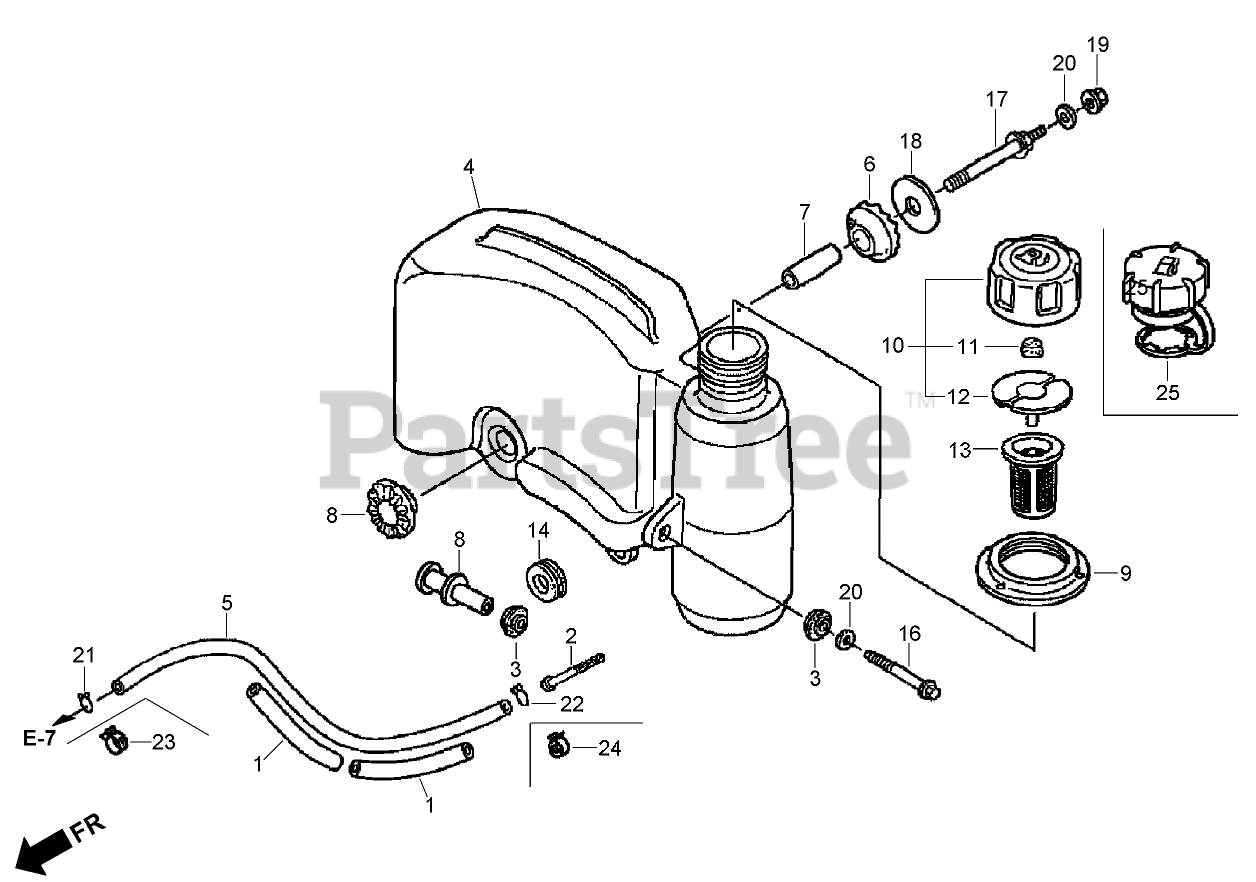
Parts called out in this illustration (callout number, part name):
1	SUPPORTER-RUBBER (107 mm)
2	FILTER-FUEL
3	RUBBER-SETTING, TANK
4	TANK-FUEL (Engine Serial No. Up To 1036455)
4	TANK-FUEL (Engine Serial No. From 1036456)
5	TUBE-FUEL (Engine Serial No. Up To 1011283)
5	TUBE-FUEL (FKM) (Engine Serial No. From 1011284)
6	RUBBER B-MOUNTING, TANK
7	COLLAR-SET, TANK
8	COLLAR-TANK
9	RUBBER-MOUNTING, TANK (Engine Serial No. Up To 1036455)
10	FUEL TANK CAP ASM (Engine Serial No. Up To 1036455)
11	SPONGE-BREATHER, FUEL CAP (Engine Serial No. Up To 1036455)
12	GASKET-CAP, FUEL (Engine Serial No. Up To 1036455)
13	GAUGE-LEVEL, FUEL
14	CUSHION-FENDER, R R
16	BOLT-FLANGE (6X47) (C T200)
17	BOLT-STAY, TANK
18	WASHER-MOUNTING, TANK
19	NUT-FLANGE (6 mm)
20	WASHER-PLAIN (6 mm)
21	CLIP-TUBE (B8) (Engine Serial No. Up To 1011283)
22	CLIP-TUBE (C11) (Engine Serial No. Up To 1011283)
23	CLAMP-TUBE (D8) (Engine Serial No. From 1011284)
24	CLAMP-TUBE (D105) (Engine Serial No. From 1011284)
25	FUEL TANK CAP ASM (Engine Serial No. From 1036456)
